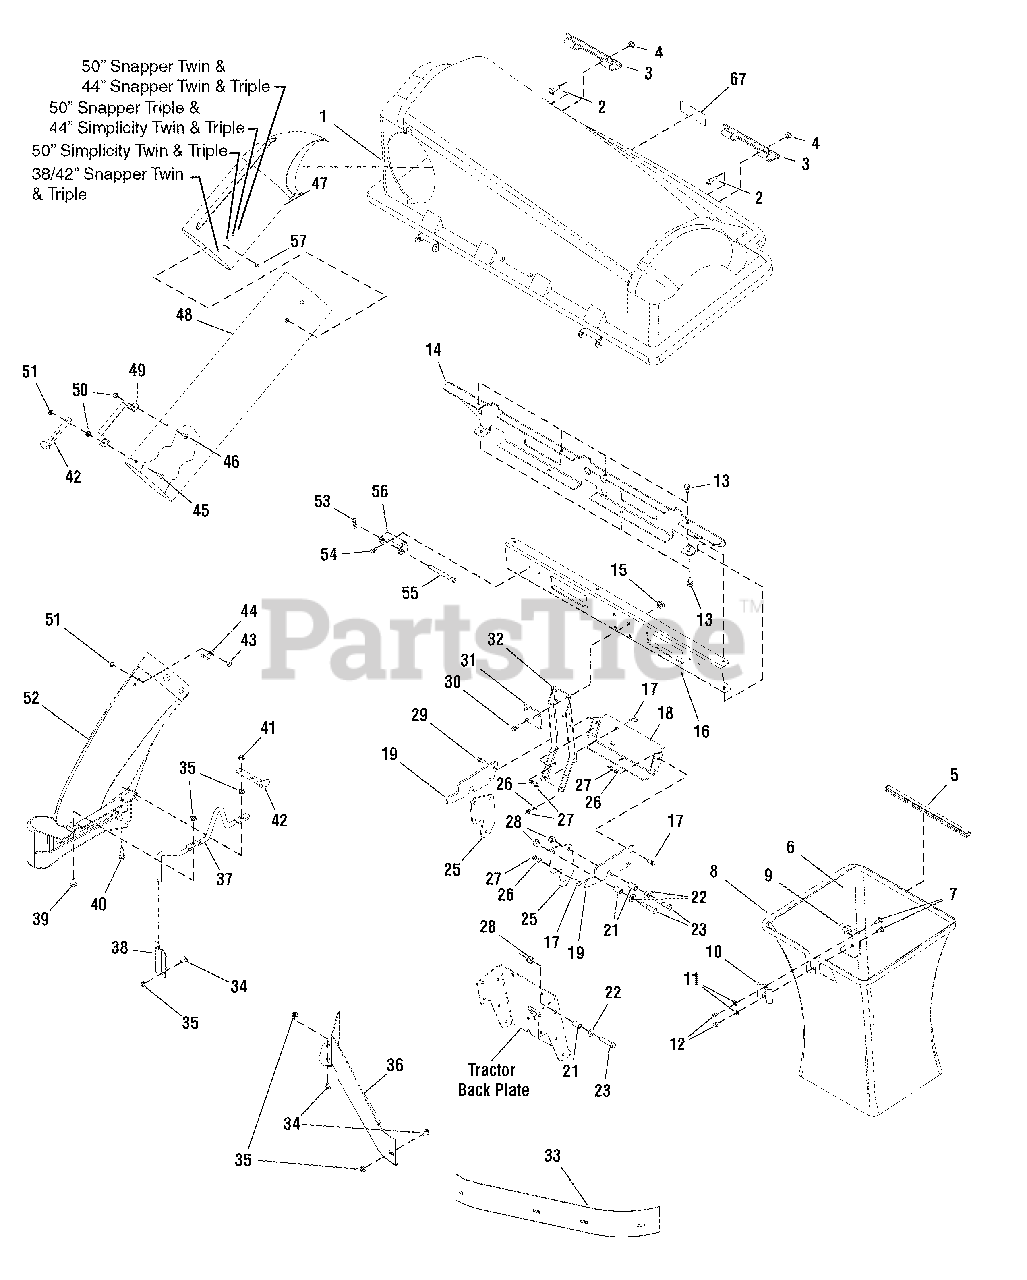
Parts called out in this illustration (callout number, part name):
1	COVER ASSEMBLY, Triple Catcher
2	SCREW, Truss Head Phillips, 10 - 24 x 3/4
3	HANDLE, Plastic
4	NUT, Hex Lock, 10-24 w/Nylon Insert
5	CLIP, Tube Grass Bag
6	BAG, Triple Regular
7	BOLT, Carriage, 5/16 - 18 x 3/4, G5
8	HOOP, Triple
9	HANGER, Grass Bag
10	CLAMP, Grass Bag Plain
11	LOCKWASHER, Spring, 5/16
12	NUT, Hex, 5/16 - 18
13	SCREW, Hex Washer Head Taptite, 5/16 - 18 x 3/4
14	BRACKET, Tab Cross Support Triple
15	NUT, Hex Whiz Lock Flange, 3/8 - 16
16	CHANNEL, Cross Support Triple
17	CAPSCREW, Hex, 3/8 - 16
18	BRACKET, LOWER
19	SUPPORT, SIDE HITCH
21	SPACER
22	WASHER, Flat
23	CAPSCREW, Hex Head, 1/2 - 13 x 2 1/2
25	PLATE, SIDE GRASS CATCHER
26	LOCKWASHER, Spring, 3/8
27	NUT, Hex, 3/8-16
28	NUT, Hex, Lock 1/2-13
29	CAPSCREW, Hex Head, 3/8 - 16 x 1 1/4
30	CAPSCREW, Whiz, 3/8 - 16 x 1.00
31	PLATE, Reinforcement, Upright
32	SUPPORT, UPRIGHT
33	BAFFLE, Blowout L.H. 50" Mower Deck
33	BAFFLE, Blowout L.H. 44" Mower Deck
34	BOLT, Carriage, 5/16 - 18 x 5/8
35	NUT, Hex Whiz Lock Flange, 5/16 - 18
36	BAFFLE, Blowout R.H. 50" Mower Deck
36	BAFFLE, Blowout R.H. 44" Mower Deck
37	ROD, Boot Mount, Deflector Prop, 44/50"
38	PLATE, Chute Rod
39	SCREW, Hex Head, 5/16 - 18 x 3/4
40	SCREW, Hex Whiz Lock Flange, 5/16 - 18 x 1-1/4
41	NUT, Hex Flange Two-Way Lock, 5/16 - 18
42	STRAP, Hood
43	BOLT, Carriage, 1/4 - 20 x 5/8
44	PIN, Latch
45	SCREW, 1/4 - 20 x 1
46	SCREW, 1/4 - 20 x 1/2
47	ELBOW, Upper Tube Poly
48	TUBE, Clear Poly
49	HANDLE, Connect Tube
50	NUT, Hex Keps, 1/4 - 20
51	NUT, Hex Flange Top-Lock, 1/4 - 20
52	TUBE, Boot Poly
53	CLIP, Hair Pin
54	SCREW, Hex Washer Head Taptite, 1/4 - 20 x 1/2
55	PIN, Cover Hinge
56	PIVOT, Hinge
57	SCREW, 1/4 x 3/4
58	STICKER, Serial w/Bar Code
59	MYLAR OVERLAY
67	DECAL, Warning Thrown Objects
